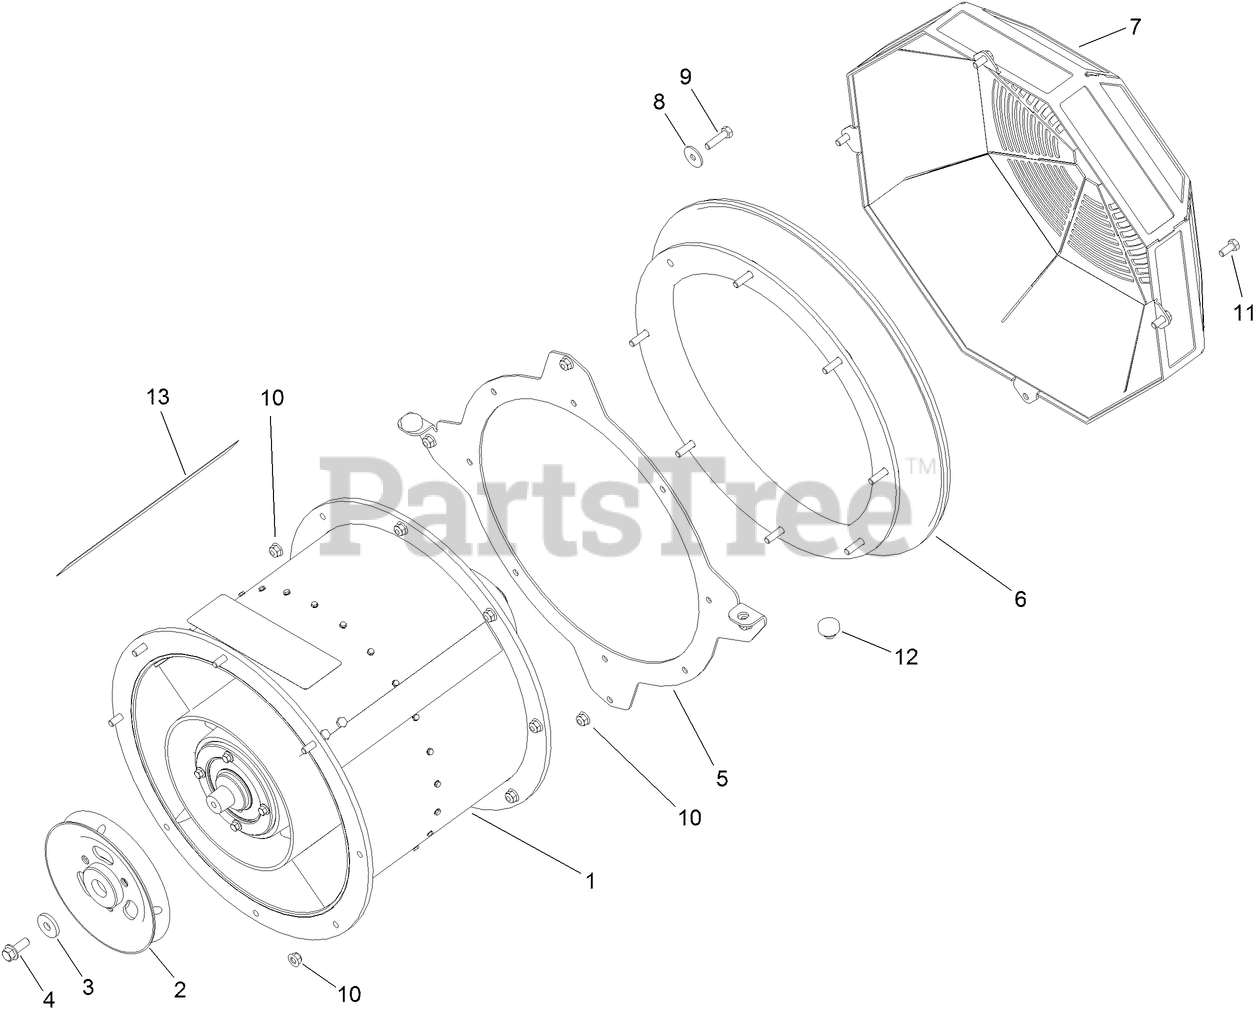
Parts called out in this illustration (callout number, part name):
1	TURBINE ASM
2	PULLEY
3	WASHER
4	SCREW-HHF
5	BRACKET-GUARD
6	BELL-INLET
7	GUARD-FAN
8	WASHER-PIVOT
9	SCREW-HH
10	NUT-HF, NI
11	SCREW-HH
12	BUMPER-RUBBER
